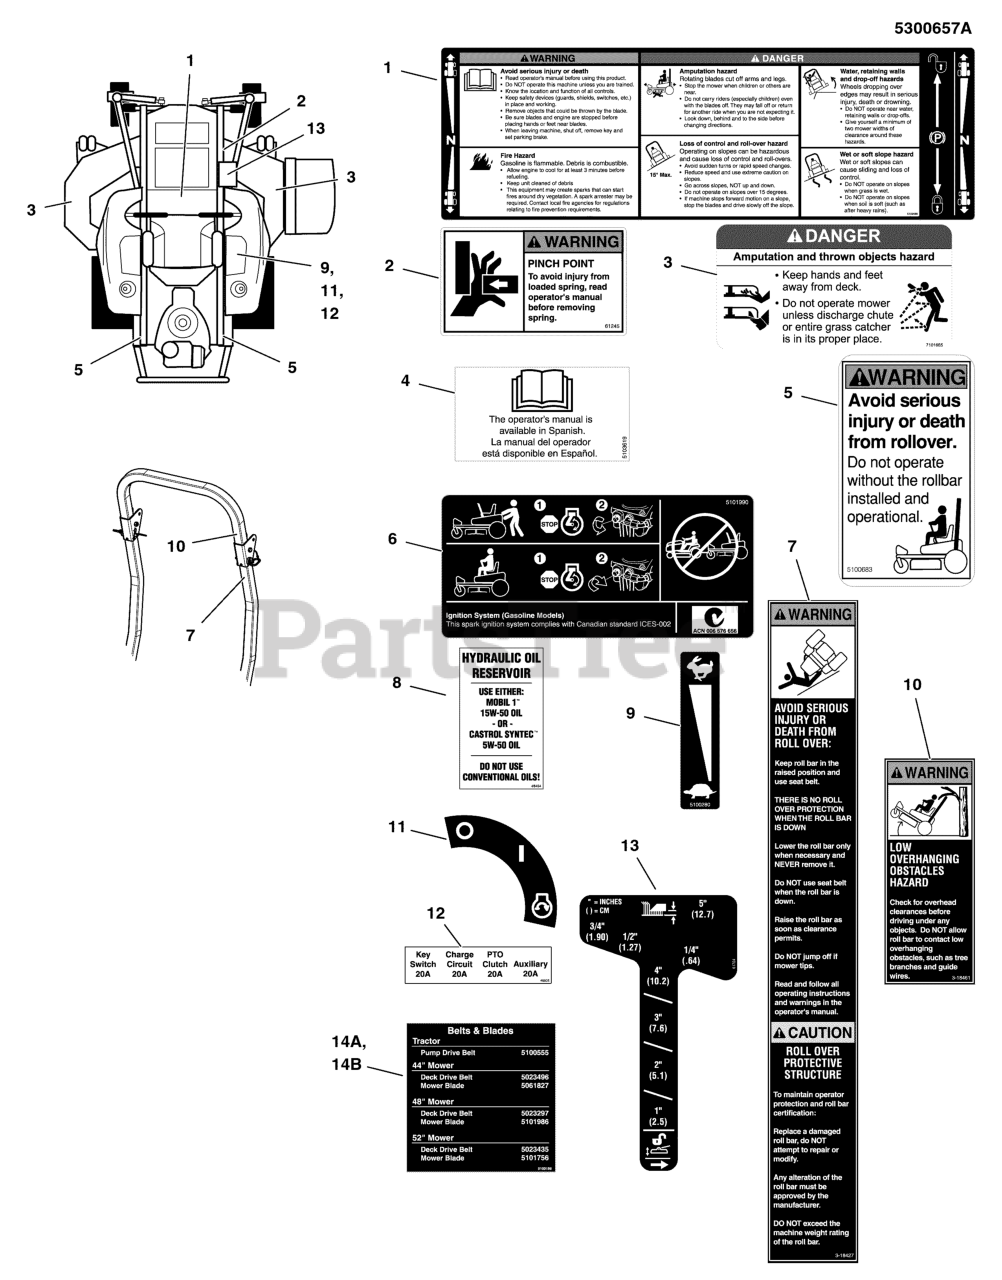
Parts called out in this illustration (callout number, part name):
1	DECAL, MAIN SAFETY
2	DECAL, PINCH POINT
3	DECAL, DANGER DO NOT OPERATE W/O DEFLECT
4	DECAL, MANUAL AVAIL IN SPANISH
5	DECAL, WARNING, ROLL BAR
6	DECAL, CZT HYRDO RELEASE
8	DECAL, OIL RESEVOIR
9	DECAL, THROTTLE CONTROL
10	DECAL, WARNING OVERHANG, ROPS
11	DECAL, IGNITION SWITCH
12	DECAL, FUSE LOCATION
13	DECAL-HEIGHT CITATION
14A	* DECAL, BELT & BLADE, IS1500Z
14B	* DECAL, BELT & BLADE, IS1500Z
